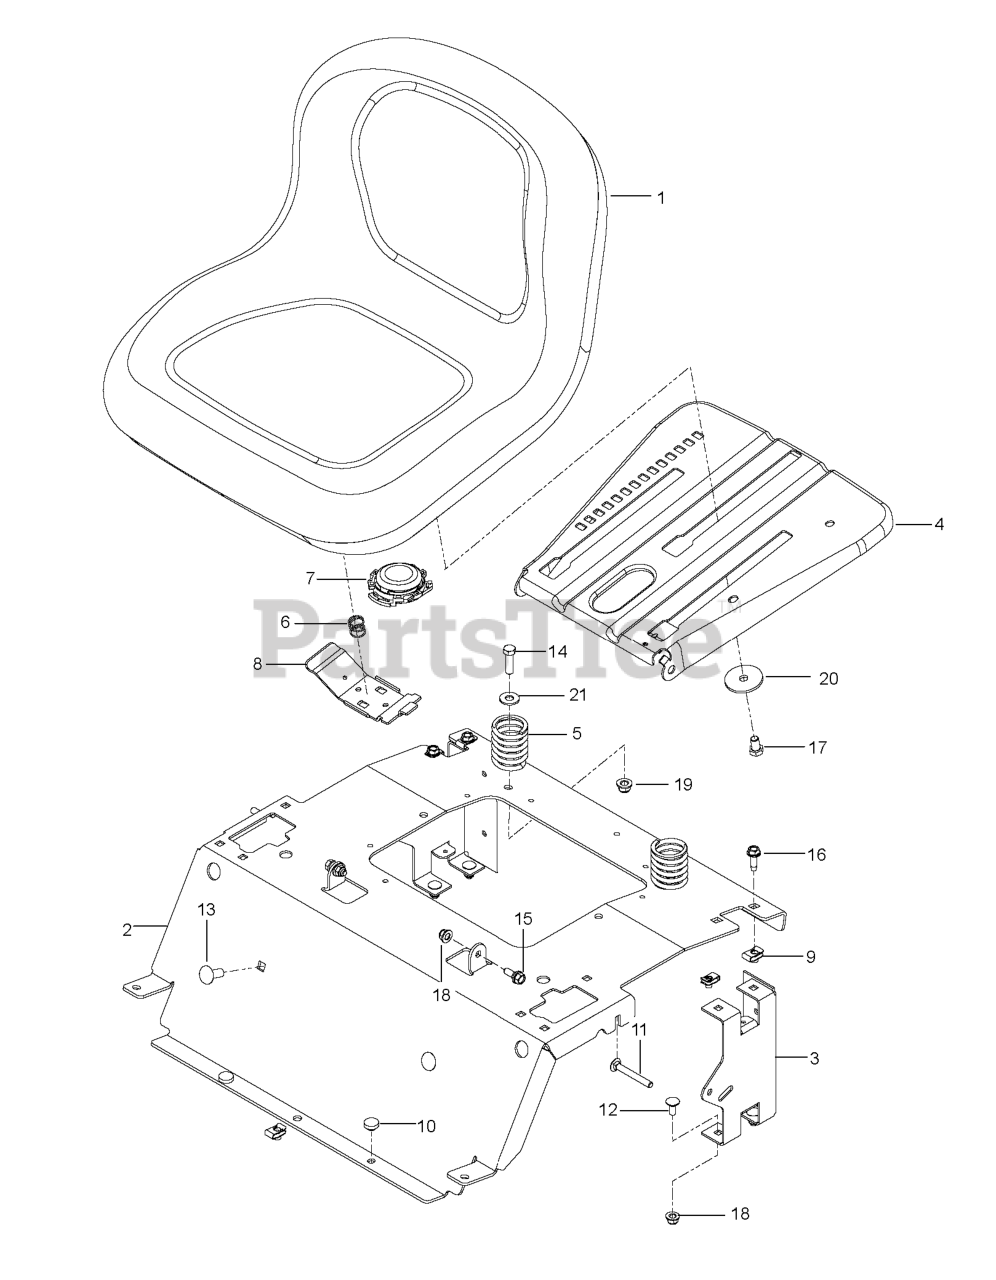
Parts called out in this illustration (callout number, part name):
1	SEAT.TH150.MS498.GRY.HUSQ.TEX
2	SUPPORT, SEAT ORANGE
3	SUPPORT, REAR SEAT, BLACK
4	PAN.ASM.SEAT.3PT
5	SPRING COMPRESSION
6	SPRING.LATCH.SEAT.TEX
7	SWITCH, SEAT N/C
8	HANDLE.SLIDE.SEAT.TEX.BLACK
9	U-CLIP 5/16-18 NUT RETAINER
10	GROMMET, BUMPER
11	RHSNB 5/16-18 X 2-1/2 GR5 ZD
12	BOLT 5/16C X 3/4" CARRIAGE
13	BOLT D
14	BOLT
15	BOLT, SHOULDER
16	SCREW.THDROL.5/16-18X3/4.TTY
17	HCS 3/8-16 X 5/8 GR 5 ZD
18	5/16-18 NYLOC FLANGE NUT
19	NUT 3/8-16 HEX FLG NYLOC ZD
20	WASHER, 3/8 SPEC
21	RP WASHER 3/8 FLAT
